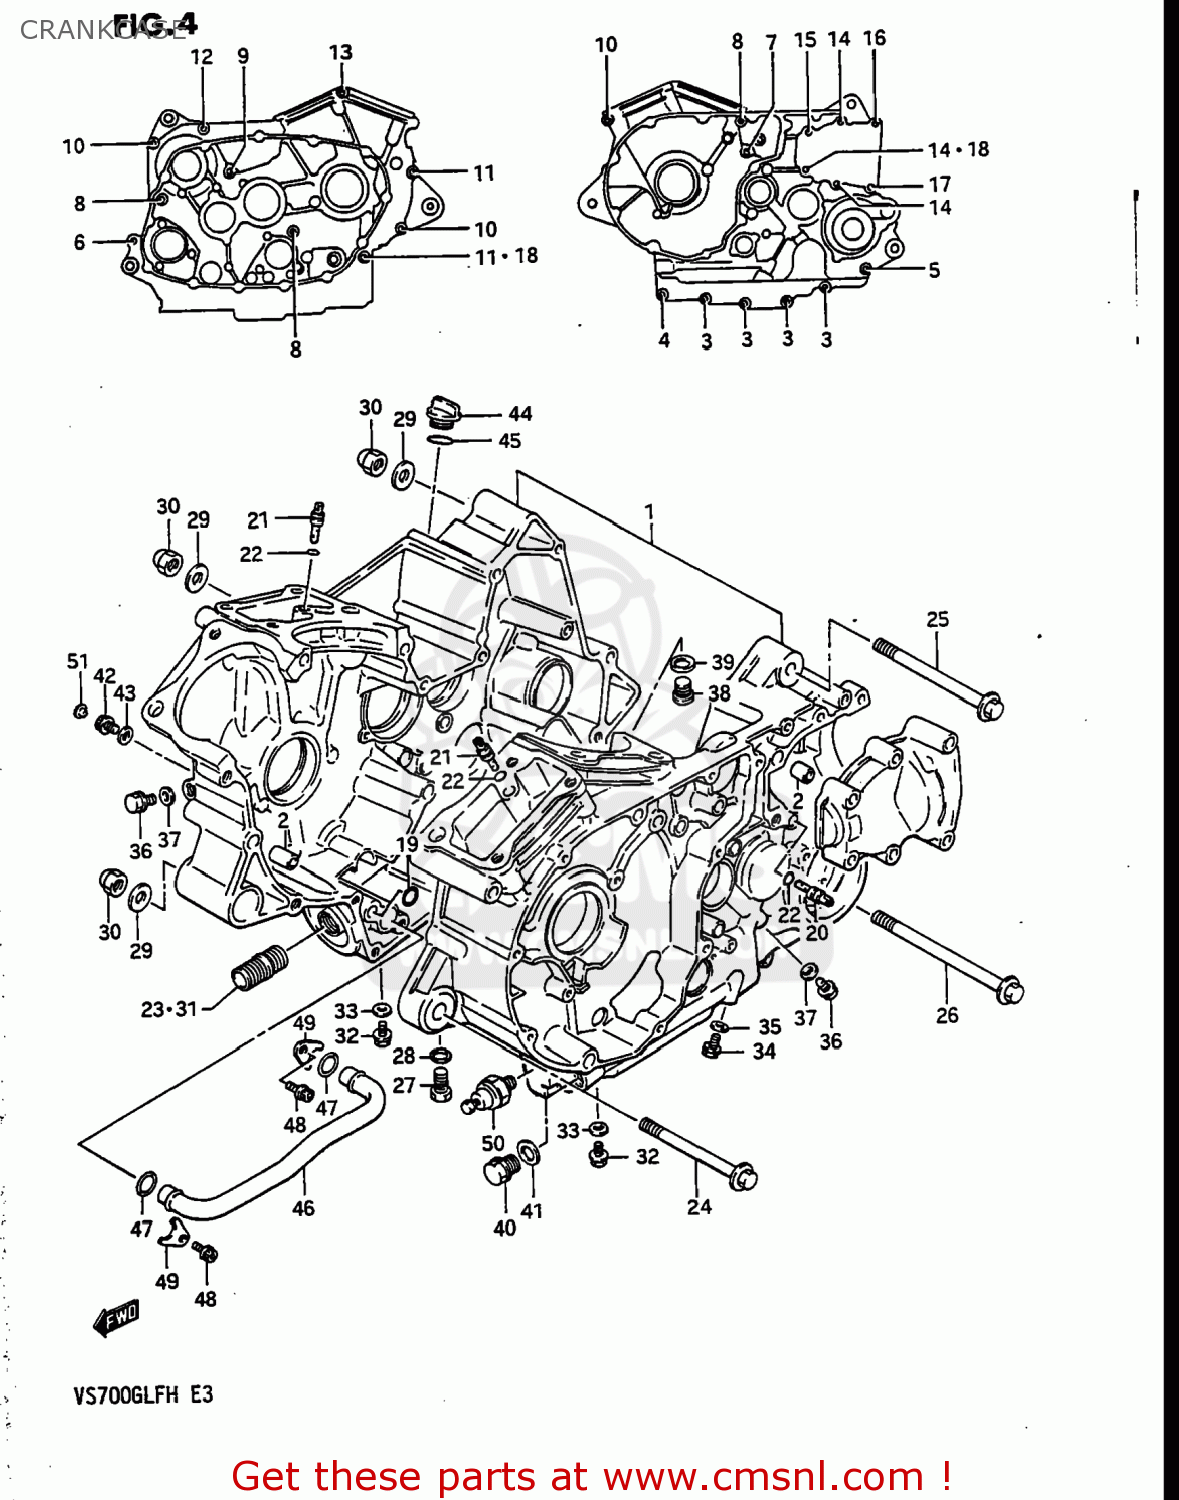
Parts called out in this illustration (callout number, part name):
1	CRANKCASE SET
2	PIN (11X20)(SUS)
3	BOLT
4	BOLT
5	BOLT 8X55
6	BOLT
7	BOLT 8X75
8	BOLT (8X95)
9	BOLT(8X120)
10	BOLT(8X95)
11	BOLT(8X105)
12	BOLT(8X120)
13	BOLT(8X160)
14	BOLT (8X40)
15	BOLT
16	BOLT(8X55)
17	BOLT(8X65)
18	GASKET 8.2X14X1 (NAS)
19	O-RING
20	JET,OIL GALLERY
21	JET,AIR(14)
22	O RING(D:1.2,ID:4)
23	UNION,OIL STAND
24	BOLT
25	BOLT
26	BOLT(10X150)
27	BOLT
28	GASKET(12.1X16.2X3.7) (NAS)
29	WASHER
30	NUT
31	UNION,OIL STAND
32	BOLT 8X12
33	GASKET(8.2X14X1).6 (NAS)
34	PLUG
35	GASKET(10X14X3.6) (NAS)
36	BOLT
37	GASKET(5.8X13X1.2) (NAS)
38	PLUG
39	GASKET(16X22X2) (NAS)
40	PLUG (14X12)
41	GASKET(14X19.2X2) (NAS)
42	BOLT
43	GASKET(8.2X14X1).6 (NAS)
44	PLUG
45	O RING(D:3.1,ID:16.8)
46	PIPE,OIL GALLERY
47	O RING(D:3.1,ID:14.8)
48	BOLT
49	CLAMP,OIL PIPE
50	SWITCH ASSEMBLY
51	CAP(OD:11)
